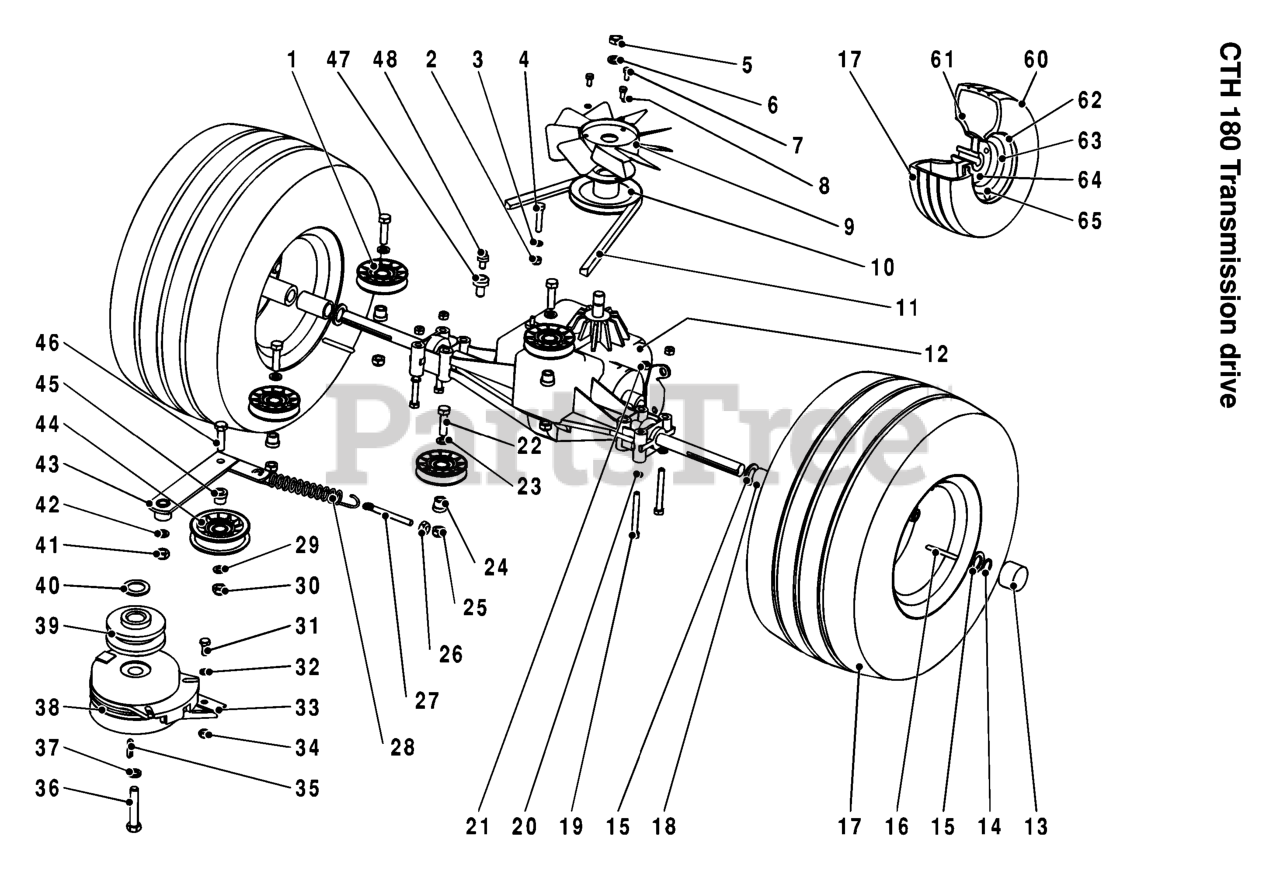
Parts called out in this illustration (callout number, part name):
1	PULLEY
14	RETAINING RING
21	NUT
23	WASHER
29	WASHER
34	NUT
37	WASHER - M12
38	CLUTCH, EL MAGNET
41	NUT
